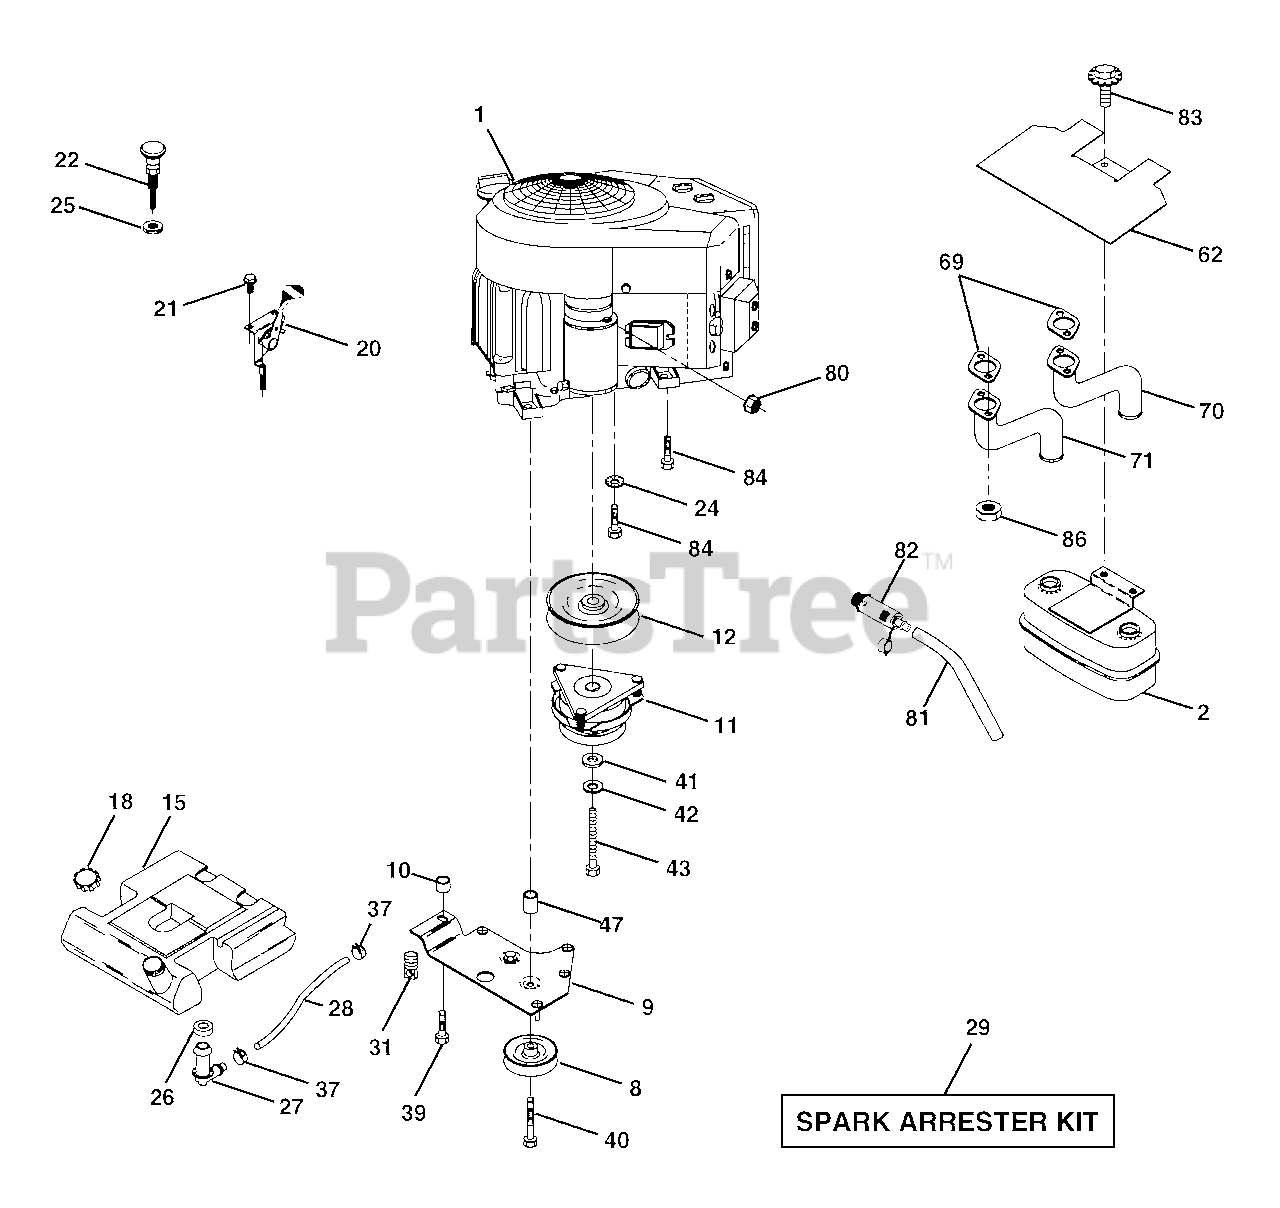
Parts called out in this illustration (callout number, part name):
2	Muffl er Side
8	Pulley V-Idler
9	Keeper Asm. Belt Engine VGT
11	Clutch Electric
12	Pulley Engine VGT Elect Clutch
15	Tank Fuel 5.0
18	Cap Fuel
20	Control Throttle
21	Screw HWHD Hi-Lo #13-16 x 3/4
22	Control Choke
24	Washer Ext Tooth 3/8
25	Nut Keps 3/8-24 Unf
27	Stem Tank Fuel
28	Fuel Line
29	Spark Arrester Kit
37	Clamp Hose
39	Screw TT 3/8-16 x 2-1/4 Unc
40	Screw TT 3/8-16 x 4 Unc
41	Washer 1-1/2 OD x 15/32 ID x .250
42	Washer Lock 7/16
43	Bolt Hex 7/16-20 x 3.75 Ga 5
62	Shield Heat Muffl er
69	Gasket
70	Tube Exhaust RH
71	Tube Exhaust LH
80	Nut Flange M8-1.25
81	Tube Drain Oil Easy
82	Plug Oil Drain
83	Bolt 5/16-18unc x 1-3/4 W/Sems
84	Screw 3/8-16 x 1-1/2
86	Nut Hex Flange Toplock M8-1.25
